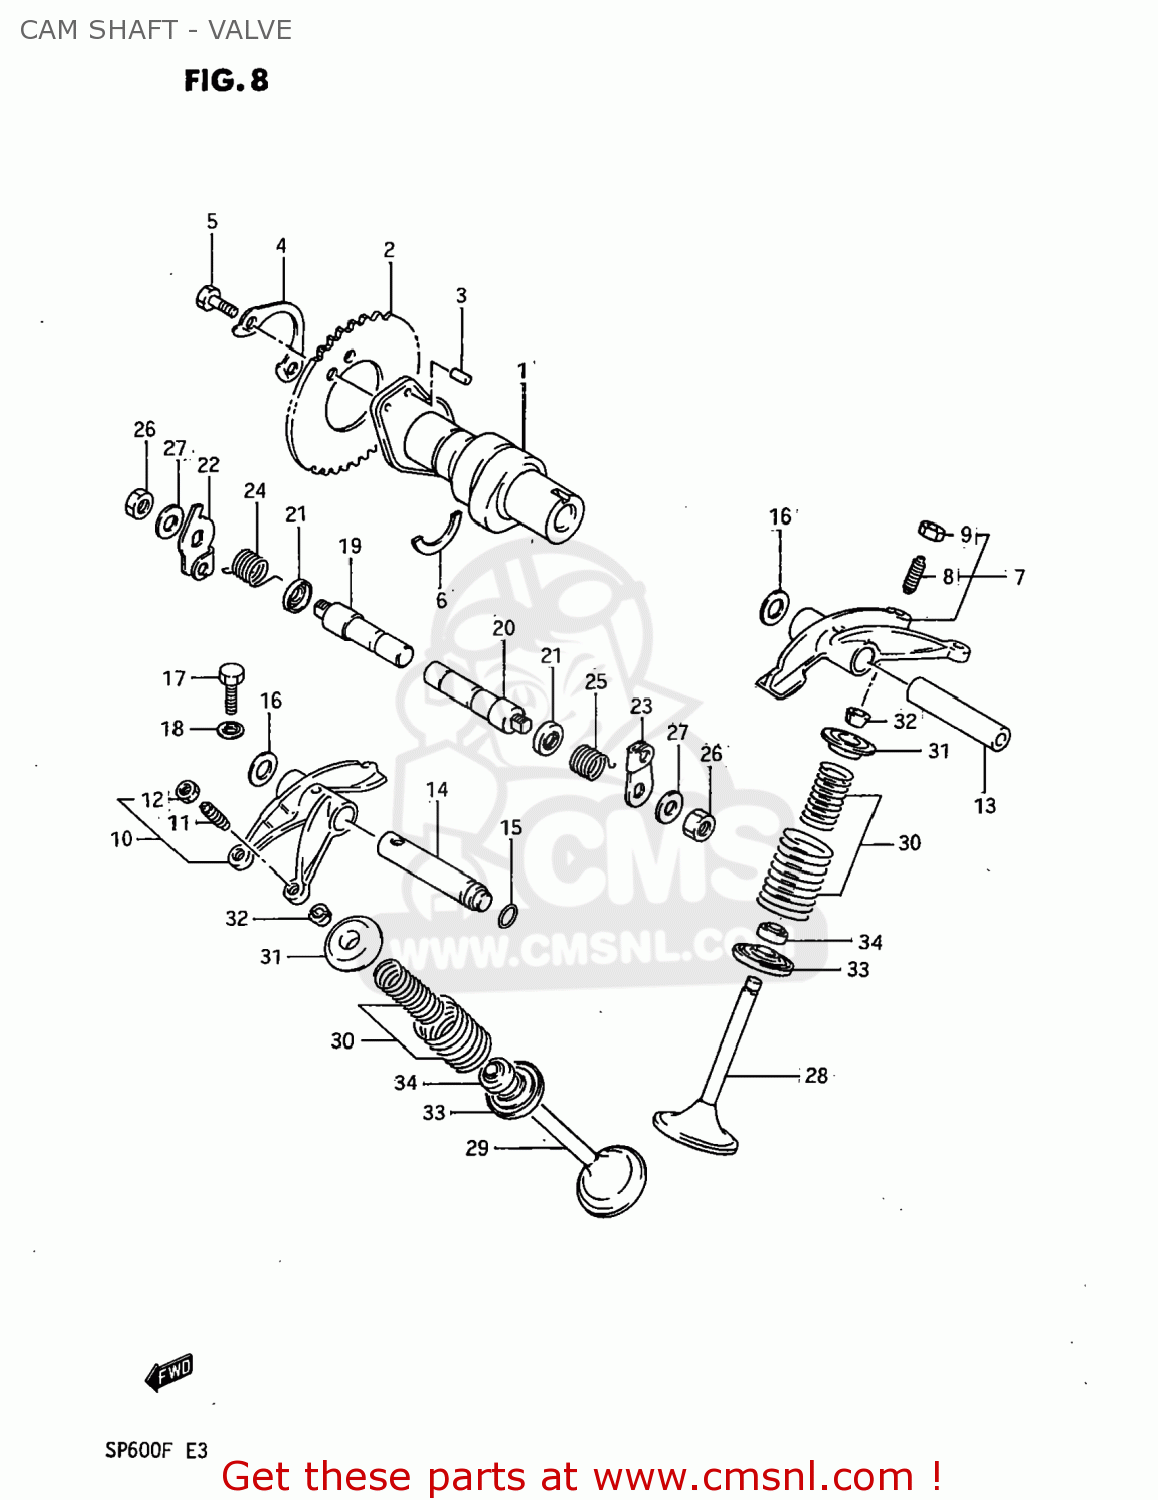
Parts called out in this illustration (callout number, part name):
1	CAMSHAFT
2	SPROCKET,CAMSHAFT(NT:42)
3	PIN
4	WASHER,CAM CHAIN SPROCKET
5	BOLT(6X12.5)
6	C RING
7	ARM,VALVE ROCKER
8	SCREW,TAPPET ADJUSTING
9	NUT,ADJUSTING SCREW
10	ARM,VALVE ROCKER EXHAUST
11	SCREW,TAPPET ADJUSTING
12	NUT,ADJUSTING SCREW
13	SHAFT,VALVE ROCKER ARM
14	SHAFT,EXHAUST VALVE ROCKER ARM
15	O RING(D:1.9,ID:8.6)
16	WASHER
17	BOLT 6X30
18	WASHER
19	SHAFT,DECOMP LH
20	SHAFT,DECOMP,L
21	OIL SEAL
22	LEVER,DECOMP SHAFT
23	LEVER,DECOMPRESSION SHAFT,LEFT
24	SPRING
25	SPRING
26	NUT 8MM
27	WASHER
28	VALVE,INTAKE
29	VALVE,EXHAUST
30	SPRING SET,VALVE
31	RETAINER,VALVE SPRING
32	COTTER VALVE
33	SEAT,VALVE SPRING
34	SEAL,OIL(7X14.4X9)
